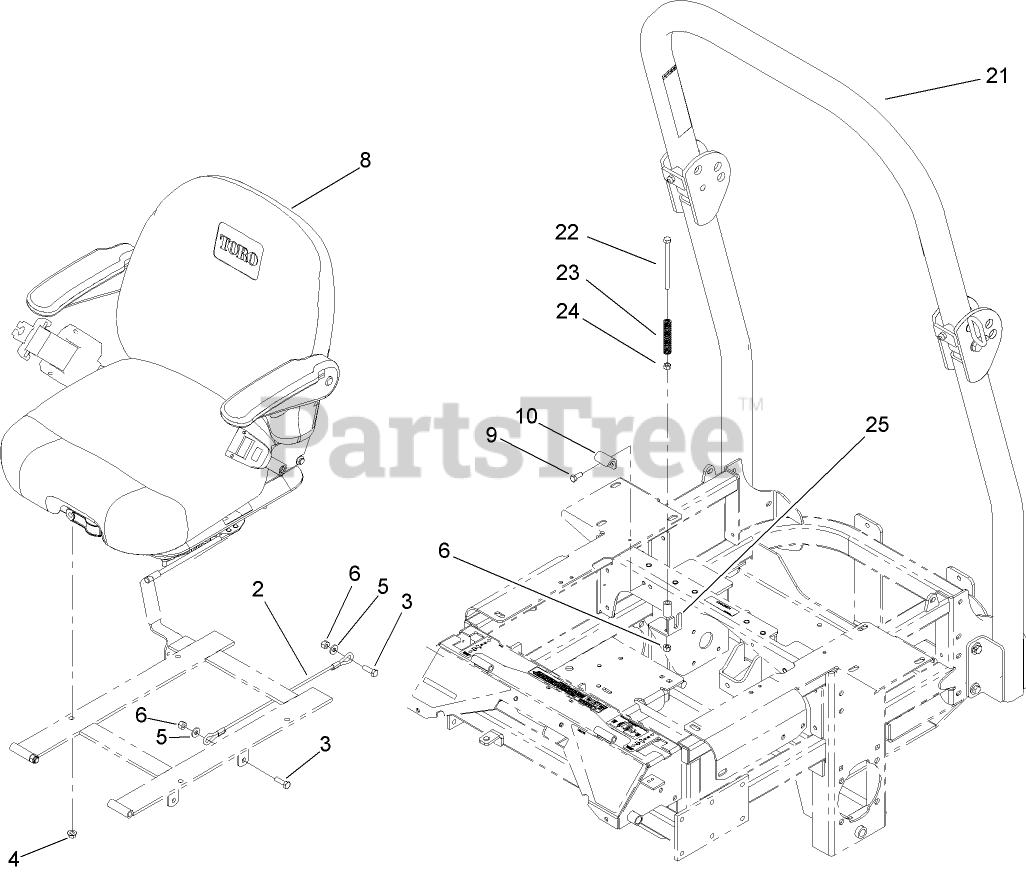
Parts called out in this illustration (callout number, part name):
2	CABLE-SEAT
3	SCREW-HH
4	NUT-HF
5	WASHER
6	NUT-LOCK, NI
8	DELUXE SEAT ASM
9	SCREW-HH
10	Catch-Latch, Seat
21	ROPS KIT
22	SCREW-HH
23	SPRING-SWITCH, SEAT
24	NUT-HEX
25	PLATE-SWITCH, SEAT
